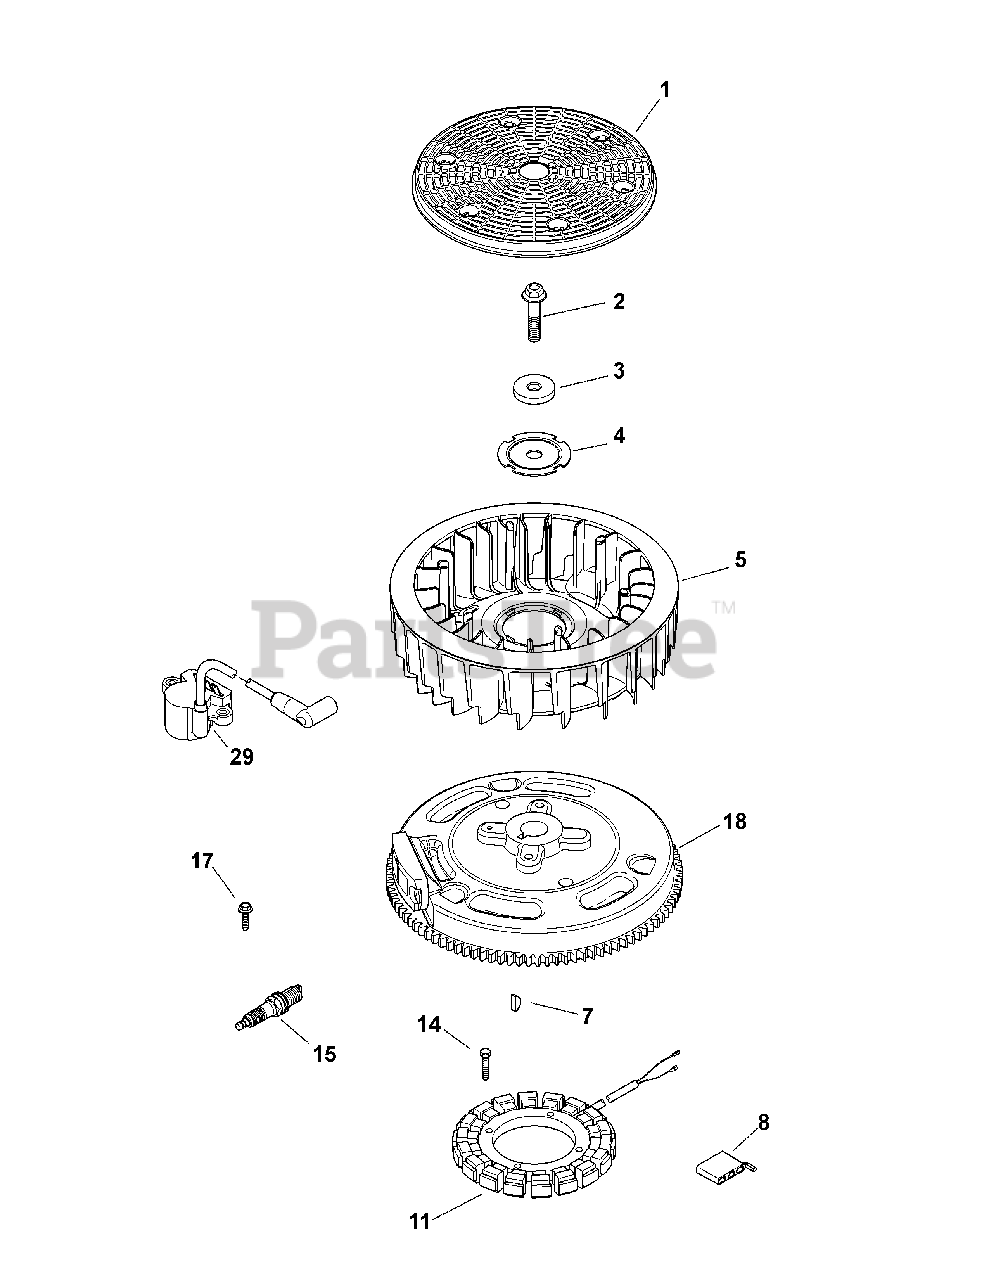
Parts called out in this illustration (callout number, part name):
2	Flg. Screw, M10 x 1.5 x 45
3	Flat Washer, 13.32
4	Fan Mounting Plate
5	Fan
7	Key, 3.16 x 5.8
11	15 Amp Stator Kit
14	Thd. Frm. Screw, M5 x 0.8 x 25
15	Spark Plug
17	Flg. Thd. Frm. Screw, M5 x .8 x 20
18	Flywheel Assembly
29	Spark Adv. Module Assembly
